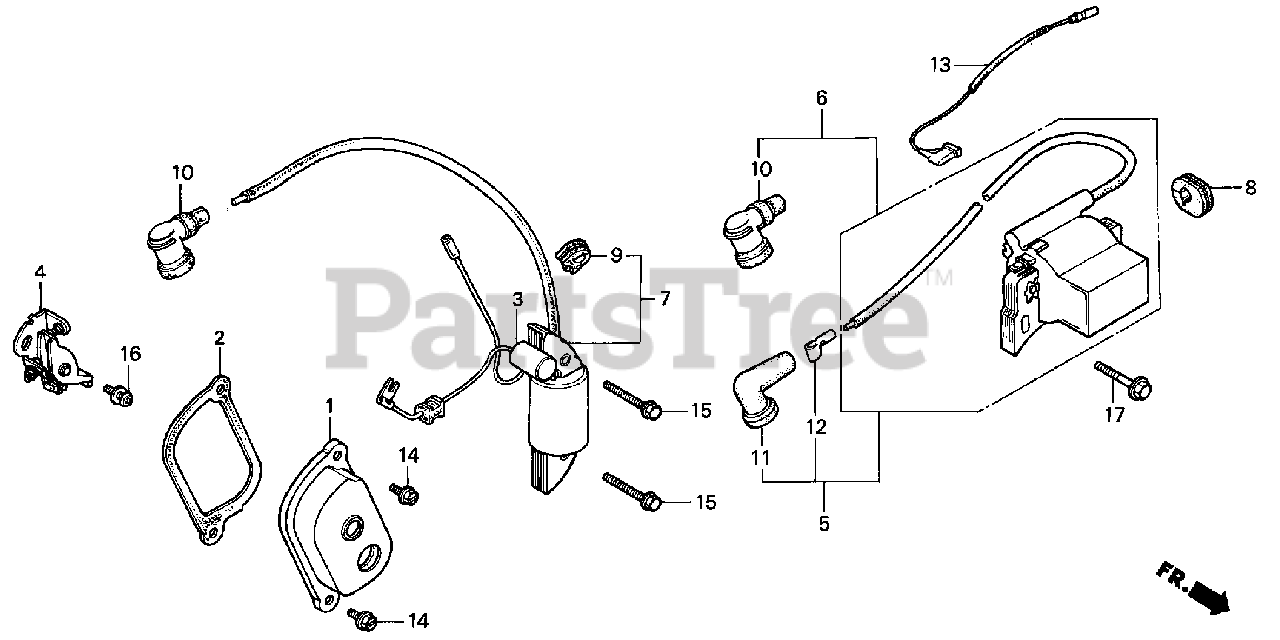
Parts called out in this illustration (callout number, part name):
1	COVER, POINTS
2	GASKET, BREAKER COVER
3	CONDENSER (NOT AVAILABLE)
4	POINTS ASSY.
7	COIL ASSY., IGNITION (NOT AVAILABLE)
9	GROMMET, WIRE
10	CAP ASSY., NOISE SUPPRESSOR
14	BOLT, FLANGE (5X10)
15	BOLT, FLANGE (5X25)
16	SCREW-WASHER (5X12)
